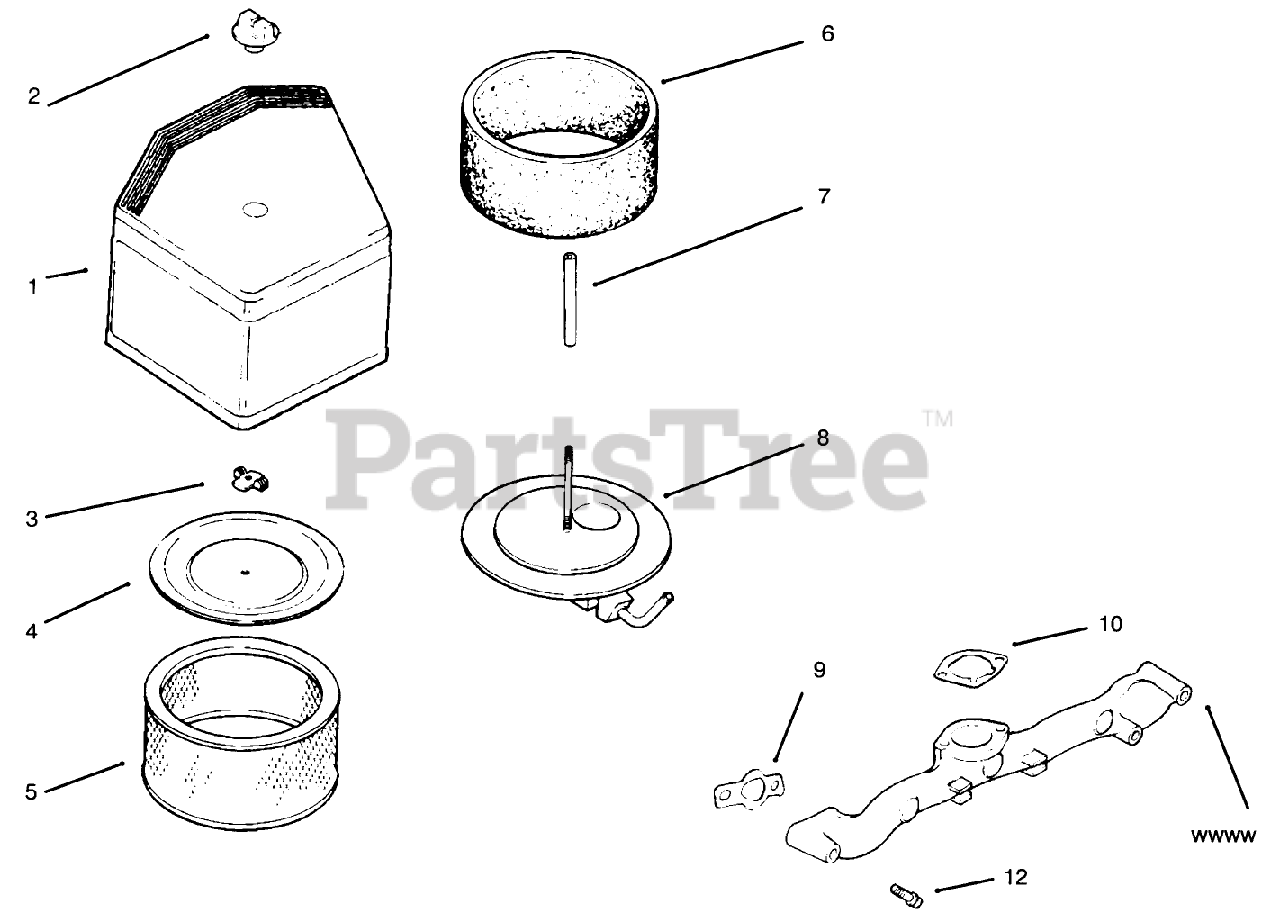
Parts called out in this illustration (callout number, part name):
1	Kit-Air Cleaner Cover (Incl. Ref. #2)
2	Knob-Cover
3	Wingnut
4	Cover-Element
5	Precleaner
6	Element
7	Seal
8	Elbow-Air Cleaner
9	Gasket-Intake, Manifold
10	Gasket-A/C Base
11	Manifold-Intake
12	Screw
